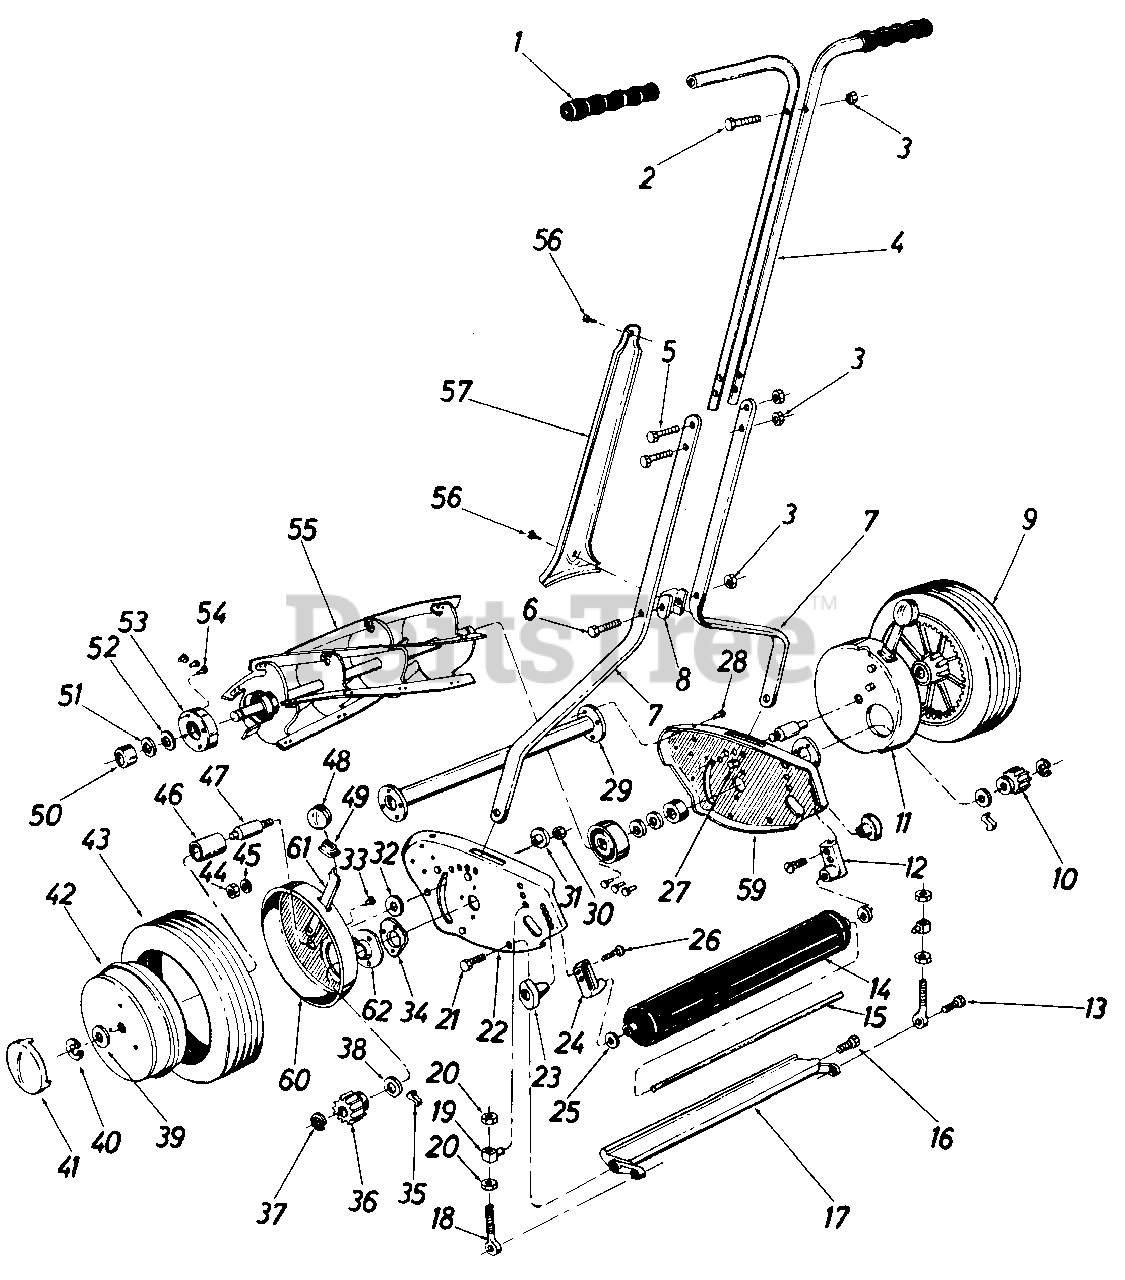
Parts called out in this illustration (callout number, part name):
1	Grip
2	Hex Scr. 5/16-18 x 1.75" Lg.
3	Hex Nut 5/16-18 Thd.
6	Hex Bolt 5/16-18 x 2.50" Lg.'
7	Handle Brace
8	Spacer
9	Wheel Ass'y.Comp.
10	Pinion Gear-R.H.
11	Gear Housing Ass'y.R.H.
12	Roller Brkt.R.H.
13	Screw-Rear
14	16" Roller
15	Roller Shaft
16	Screw-Cuter Bar- (L.H. Thd .)
17	Cuter Bar
18	Screw-Cuter Bar Adj.
19	Trunnion
20	Hex Nut 3/8-24 Thd.
21	Screw-Pivot- (R.H. Thd.)
22	End Plate Ass'y.L.H.
23	Roller Adj. Knob
24	Roller Brkt.L.H.
25	Fl-Wash. .312" I.D. x .75" O.D.
26	Roller Adj. Bolt
27	Trunnion
28	Rivet 3/16 Dia. x 3/8" Lg.
29	Spacer Tube Ass'y.
30	Hex L-Nut 5/16-24 Thd.'
31	Bushing
32	Washer
33	Hex Scr. #10-32 x 3/8" Lg.
34	Retainer
36	Pinion Gear-L.H.
37	Retaining Ring
38	Felt Washer
39	Fl-Wash. .38" I.D. x 1.25" O.D.
40	Retaining Ring
41	Hub Cap
42	Wheel Ass'y.
44	Hex Nut #10-32 Thd.
45	Washer
46	Bearing
48	Knob-Wheel Adj.
49	Dust Cover
50	Bearing
51	Felt Washer
52	Felt Washer
53	Retainer
54	Rivet 3/16 Dia. x 13/32" Lg.
55	16" Reel Ass'y.
56	Ph. Hd. Scr. #10 x .38 Lg.'
57	Handle Panel
59	End Plate Ass'y.R.H.
60	Gear Housing Ass'y.L.H.
61	Spring and Trunnion Ass'y.
62	Pinion Housing
